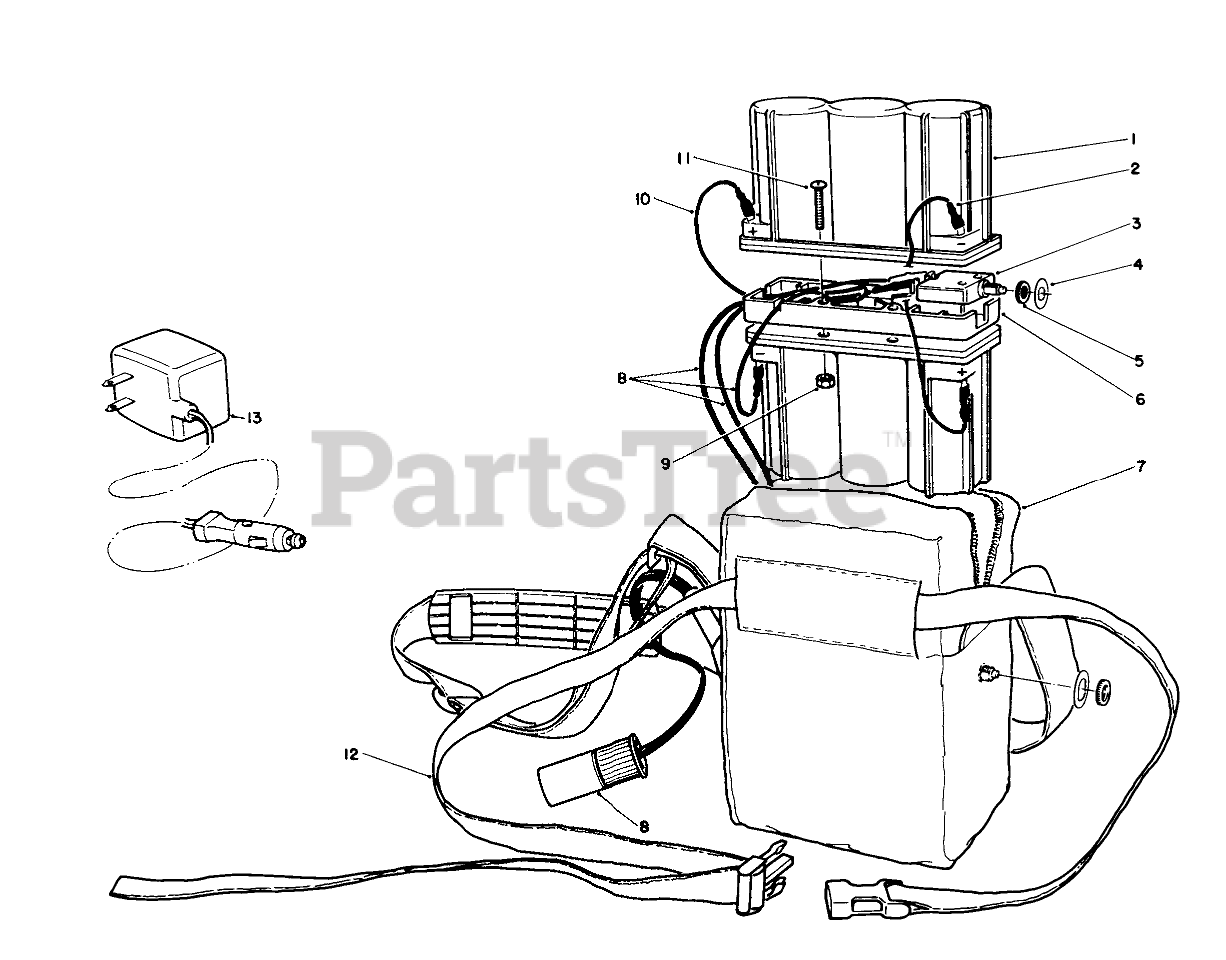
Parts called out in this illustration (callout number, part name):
1	BATTERY, 6 VOLT
2	WIRE ASSEMBLY-BATTERY
3	CKT BREAKER 15 AMP 125V
4	CIRCUIT BREAKER PLATE
5	KNURLED NUT
6	BATTERY SPACER
7	Pack-Soft
8	CORD-BATTERY PACK
9	NUT-HEX
10	WIRE ASSY-CIRCUIT BREAK
11	SCREW-PPH
12	BELT-WAIST
13	Charger 12 Volt
